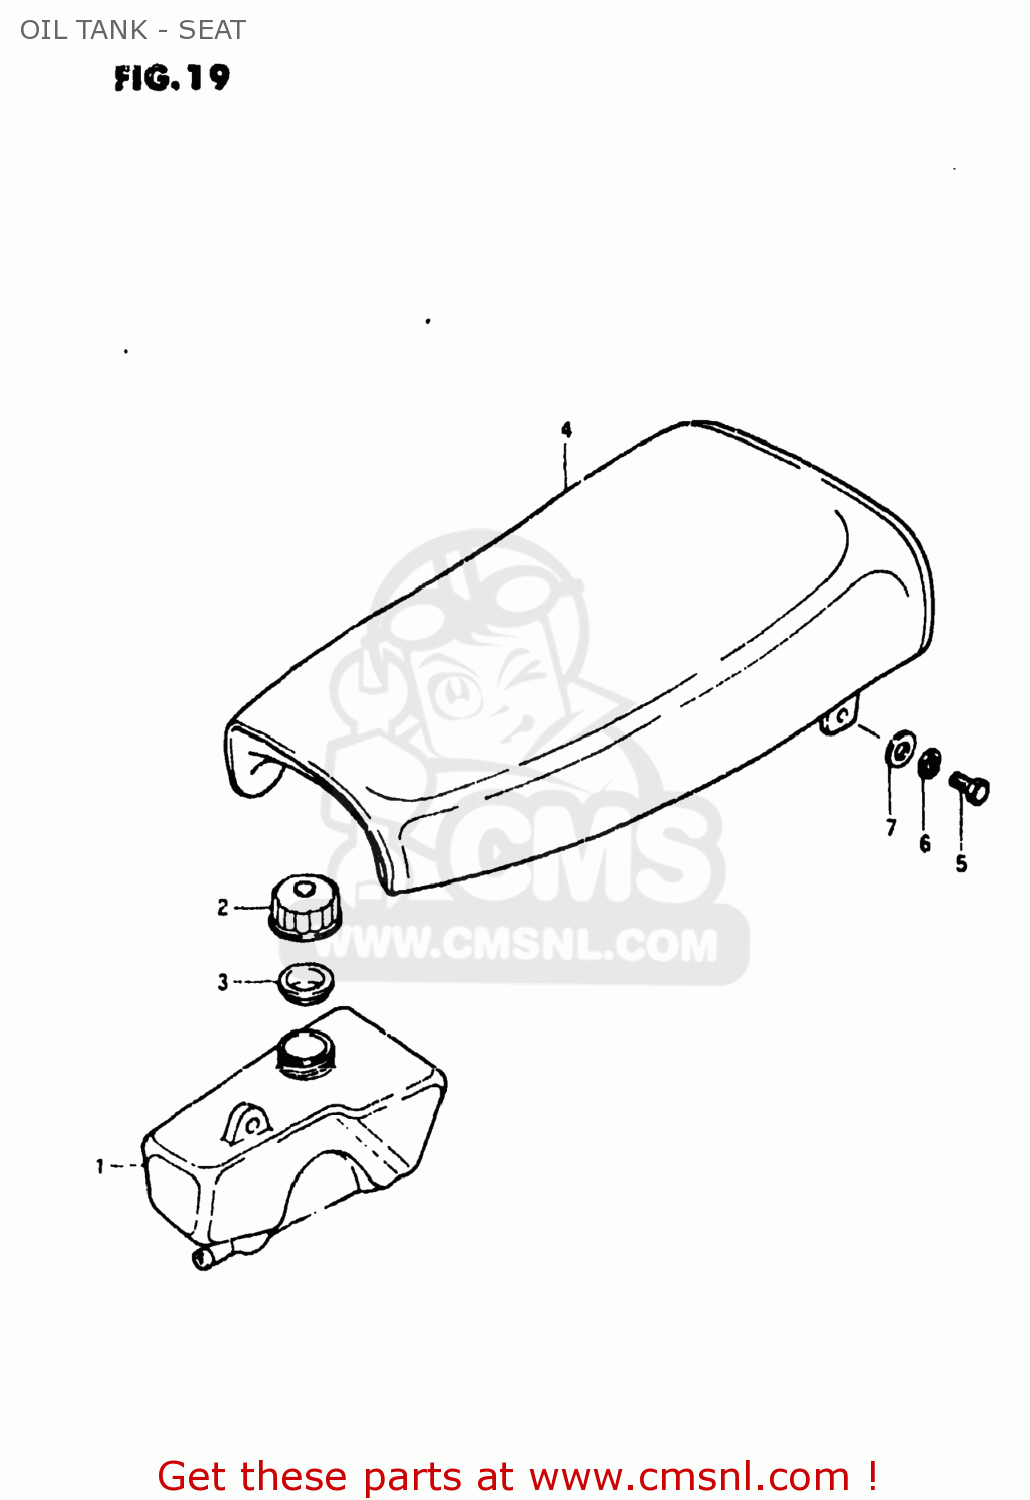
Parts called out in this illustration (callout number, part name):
1	TANK,OIL
2	CAP,OIL TANK FILLER
3	GASKET,OIL TANK (NAS)
4	SEAT ASSEMBLY
5	BOLT, UPPER
6	LOCK WASHER
7	WASHER
